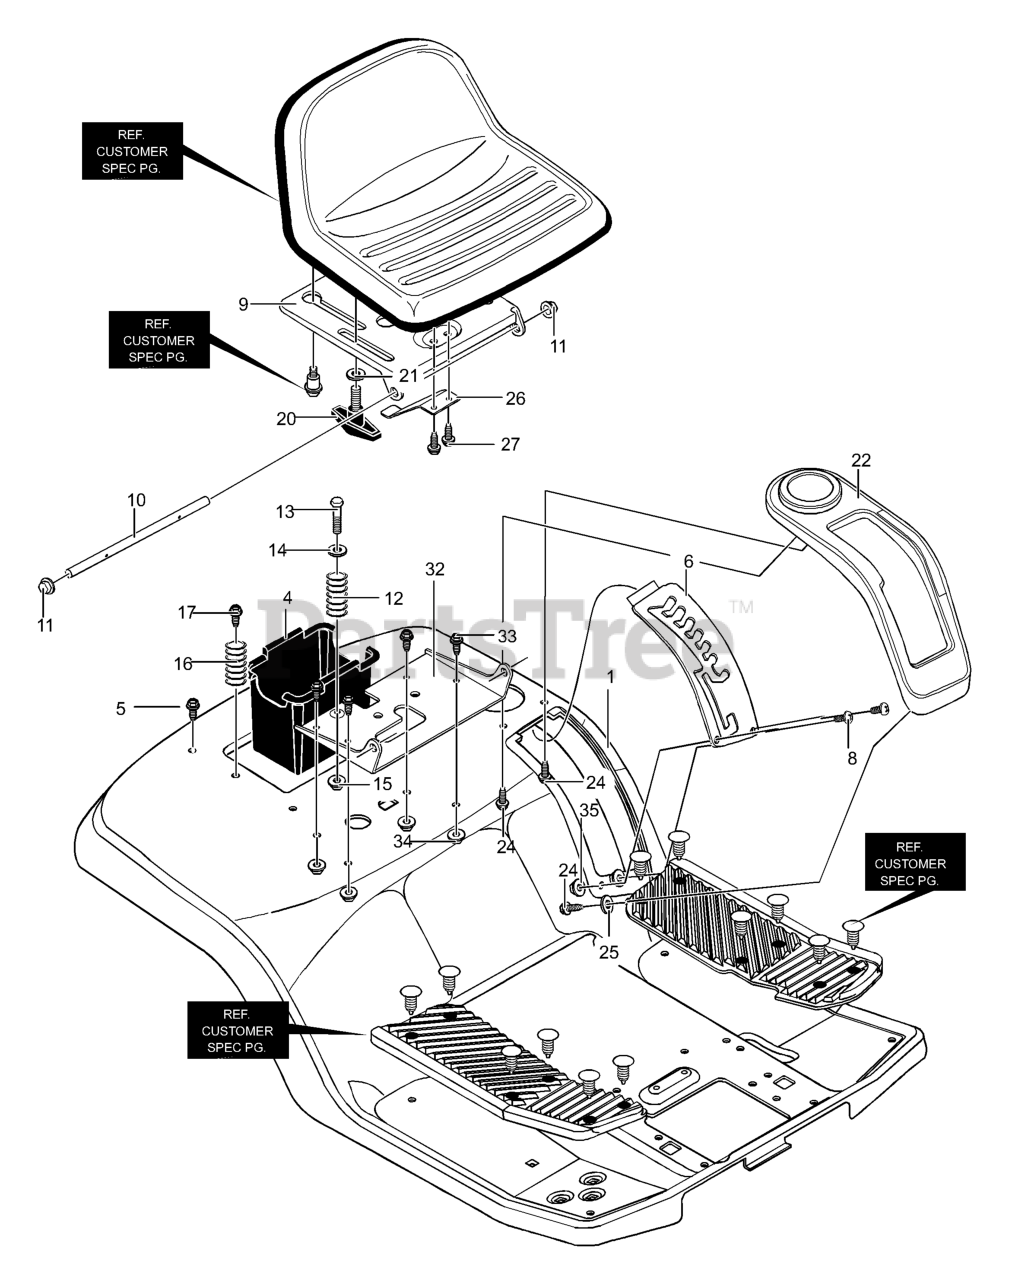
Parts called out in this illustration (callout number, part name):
1	SEAT DECK
4	CONTAINER, BATTERY
5	SCREW, 1/4-20X .63
6	PLATE, LIFT
8	SCREW, 10-24X.500
9	SUPPORT, SEAT
10	HINGE, SEAT PIVOT
11	NUT, PUSH CAP
12	SPRING, COMPRESSION
13	BOLT, SHOULDER
14	WASHER, CUP
15	NUT, 1/4-20
16	SPRING, COMPRESSION
20	BOLT, WING
26	SPRING - LEAF
27	SCREW, 1/4-20X.50
32	BRACKET, PIVOT SEAT
33	SCREW, 5/16-18 x 0.75
34	NUT, 5/16-18
35	NUT, #10-24
